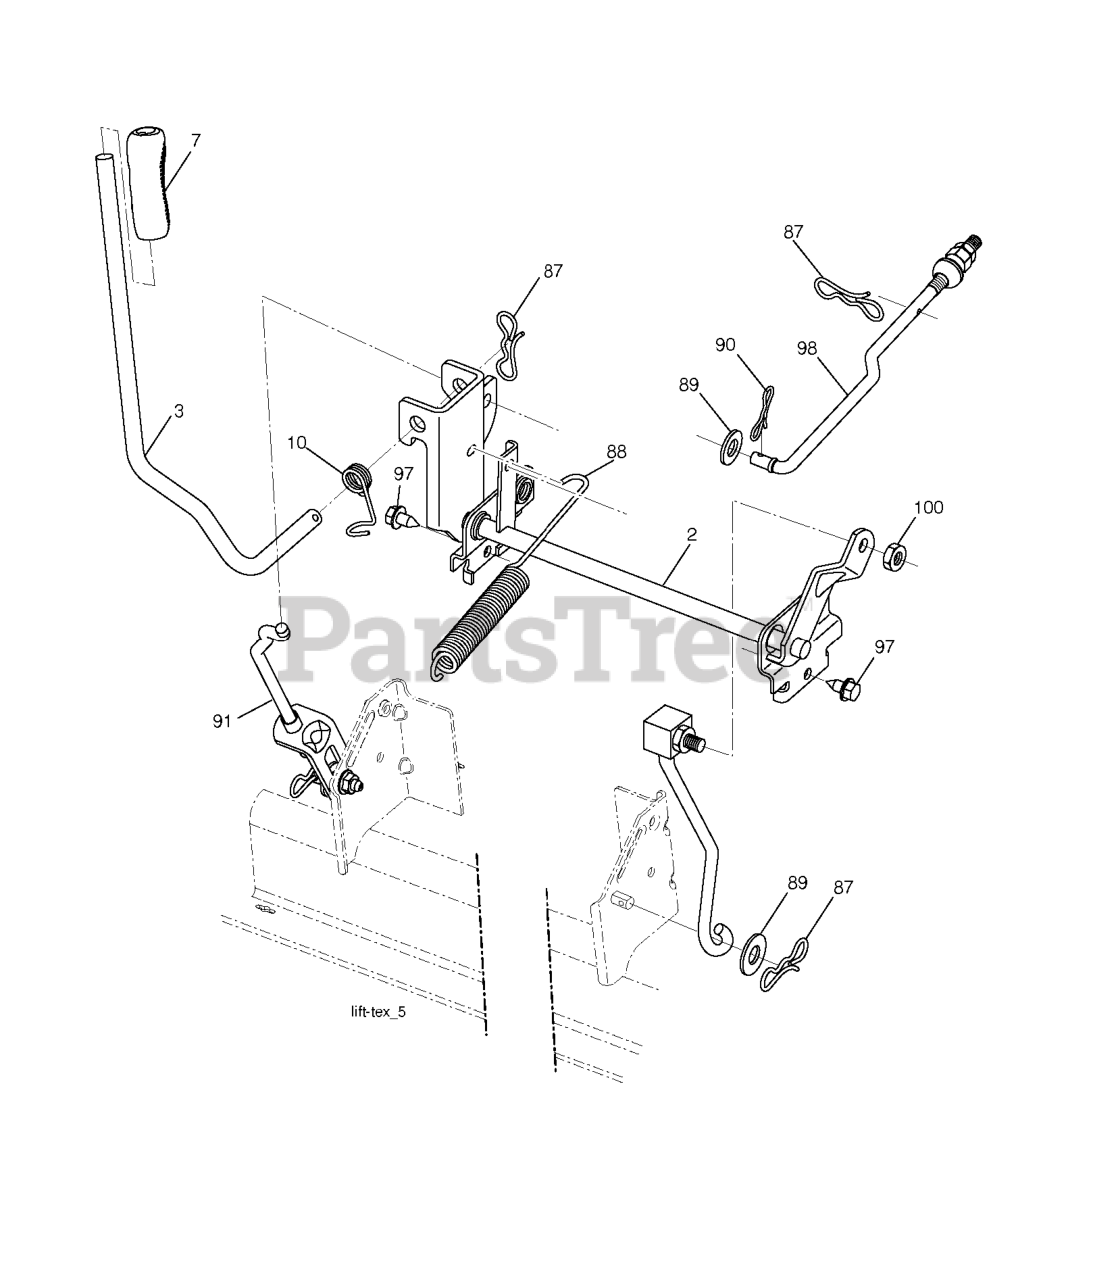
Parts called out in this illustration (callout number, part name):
2	SHAFT.ASM.LIFT.CROSS.H
3	LEVER.LIFT.HANDLE.LT
7	GRIP.HANDLE.LIFT.PVC.BLACK
10	SPRING.TORSION.LIFT.HANDLE
87	PIN.COTTER.7/16.BOW TI.
88	SPRING.LIFT.ASSIST
89	WASHER.CLEAR.ZINC
90	PIN.COTTER.5/16.BOW TI
91	ARM.SUSPENSION.MOWER.R
97	SCREW, 3/8-16X3/4
98	LINK.ASM.SUSP.FRONT.MW
100	LOCKNUT
